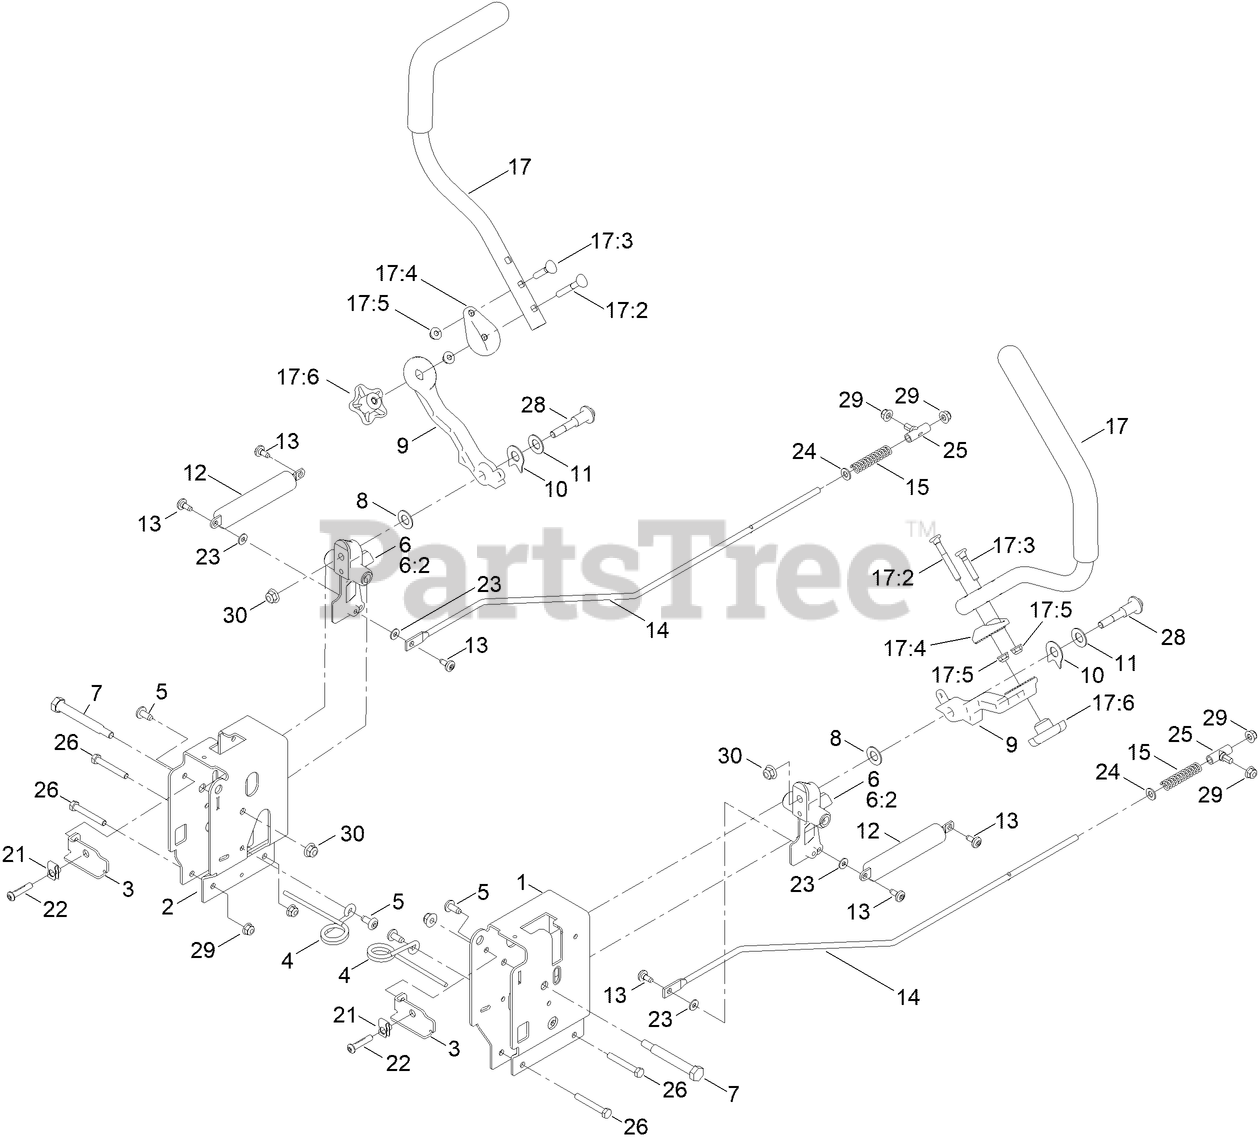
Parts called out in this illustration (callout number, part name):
1	CONTROL BOX - LH G7
2	CONTROL BOX - RH G7
3	ADJUSTMENT PLATE-CONTROL BOX
4	SPRING-TORSION
6	PIVOT ARM ASM
6:2	BUSHING-FLANGE
7	BOLT-PIVOT
8	WASHER-NYLON
9	ARM-CONTROL, 32 TEETH
10	SPACER, ANTI-ROTATION
11	WASHER-BELLEVILLE
12	DAMPER-NON CAVITATING
13	SCREW-SHOULDER
14	ROD - HYDRO, LH
15	SPRING-COMPRESSION
17	HANDLE-CONTROL, ASM
17:2	SCREW-HANDLE
17:3	SCREW-HANDLE
17:4	DISC-ADJUSTMENT HANDLE, 32 TEETH
17:5	NUT-HF
17:6	KNOB-HANDLE
22	SCREW-HSBH
23	WASHER
24	WASHER-PLAIN
25	MOUNT-ROD, HYDRO
26	SCREW-HH
28	BOLT-PIVOT
29	NUT-HF, NI
30	NUT-HF, NI
